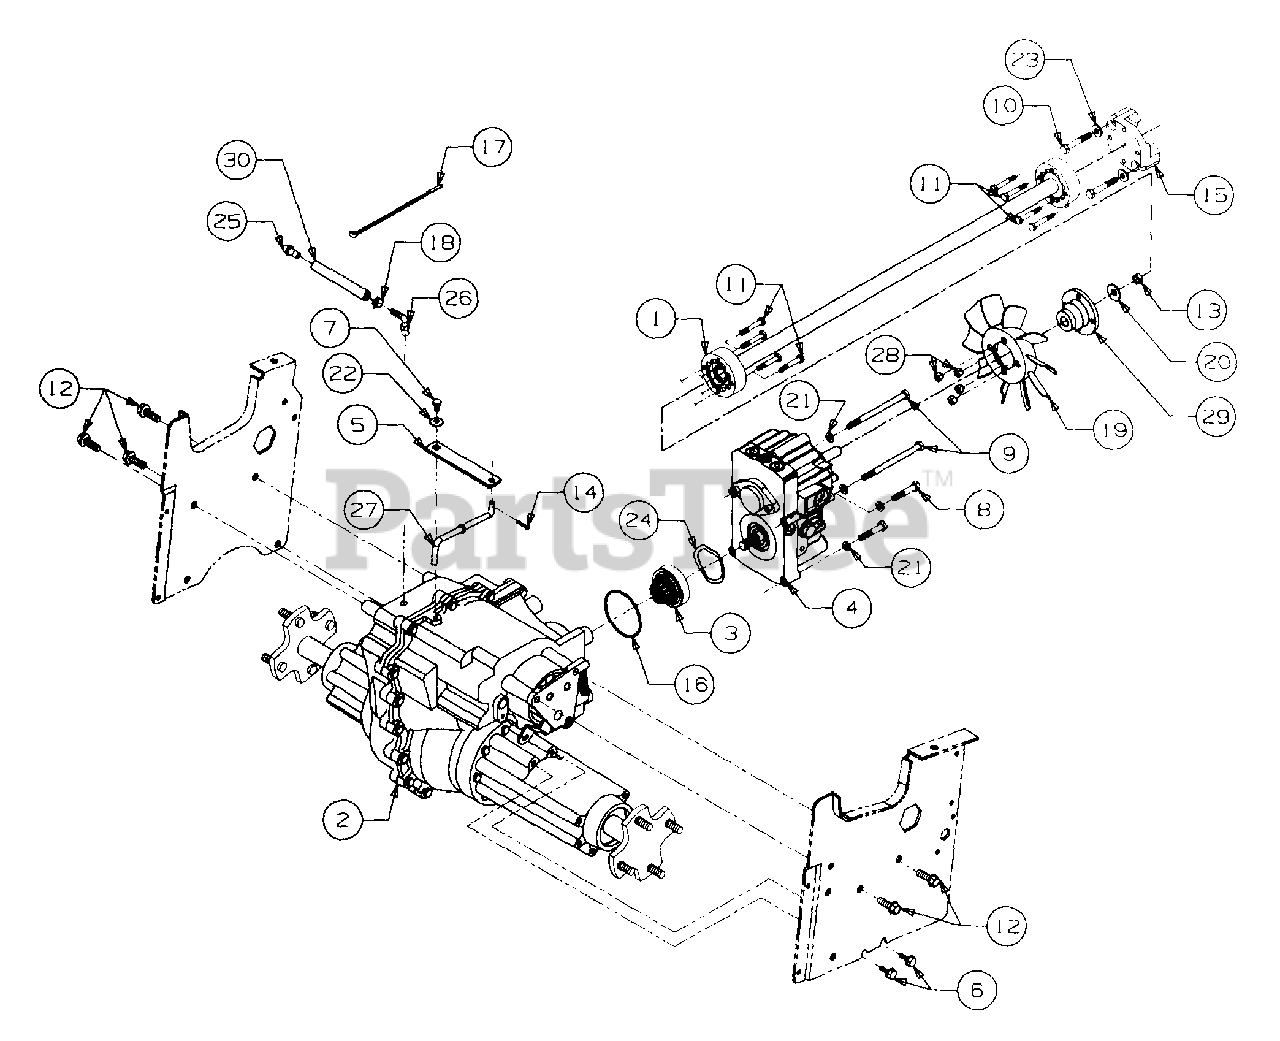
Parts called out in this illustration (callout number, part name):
1	Shaft Assy, Drive, 27.87 Lg
2	Transmission Assembly, Hydro,
3	Pinion Assy, Input
4	Pump, Hydrostatic
5	Arm, Hydro Dump
6	Screw, Hex Wash Hd Tap, 5/16-18 x .75
7	Screw, Hex Wash Hd Tap,1/4-20 x .75 GR5
8	Screw, Hex Cap, 5/16-18 x 1.75 GR5
9	Screw, Hex Cap, 5/16-18 x 4.5 GR5
10	Screw, Hex Patch, M10-1.5 x 90mm
11	Screw, Hex Patch, 1/4-20 x 1.62 GR5
12	Screw, Hex Wash Hd Tap, 3/8-16 x 1.25
13	Nut, Hex Center Lock Jam, 3/8-24
14	Pin, Internal Cotter, 5/16 Dia x 1.12
15	Adapter, Drive Shaft
16	O-Ring, 2.75 x .103
17	Tie, Self-Clinch Cable
18	Clamp, Hose
19	Fan, 10 Blade Cooling
20	Washer, Bell, .380 x .88 x .063
21	Washer, Lock, 5/16
22	Washer, Bell, .265 x .75 x .062
23	Washer, Flat, .312 x .750 x .119
24	Washer, Spring Wave, 1.96 x 2.44 x .06
26	Fitting, Elbow
27	Rod, Hydro Disengagement
28	Nut, Fan, 1/4-20
29	Adapter, Pump
30	Line, Fuel, 7 in. Lg,
